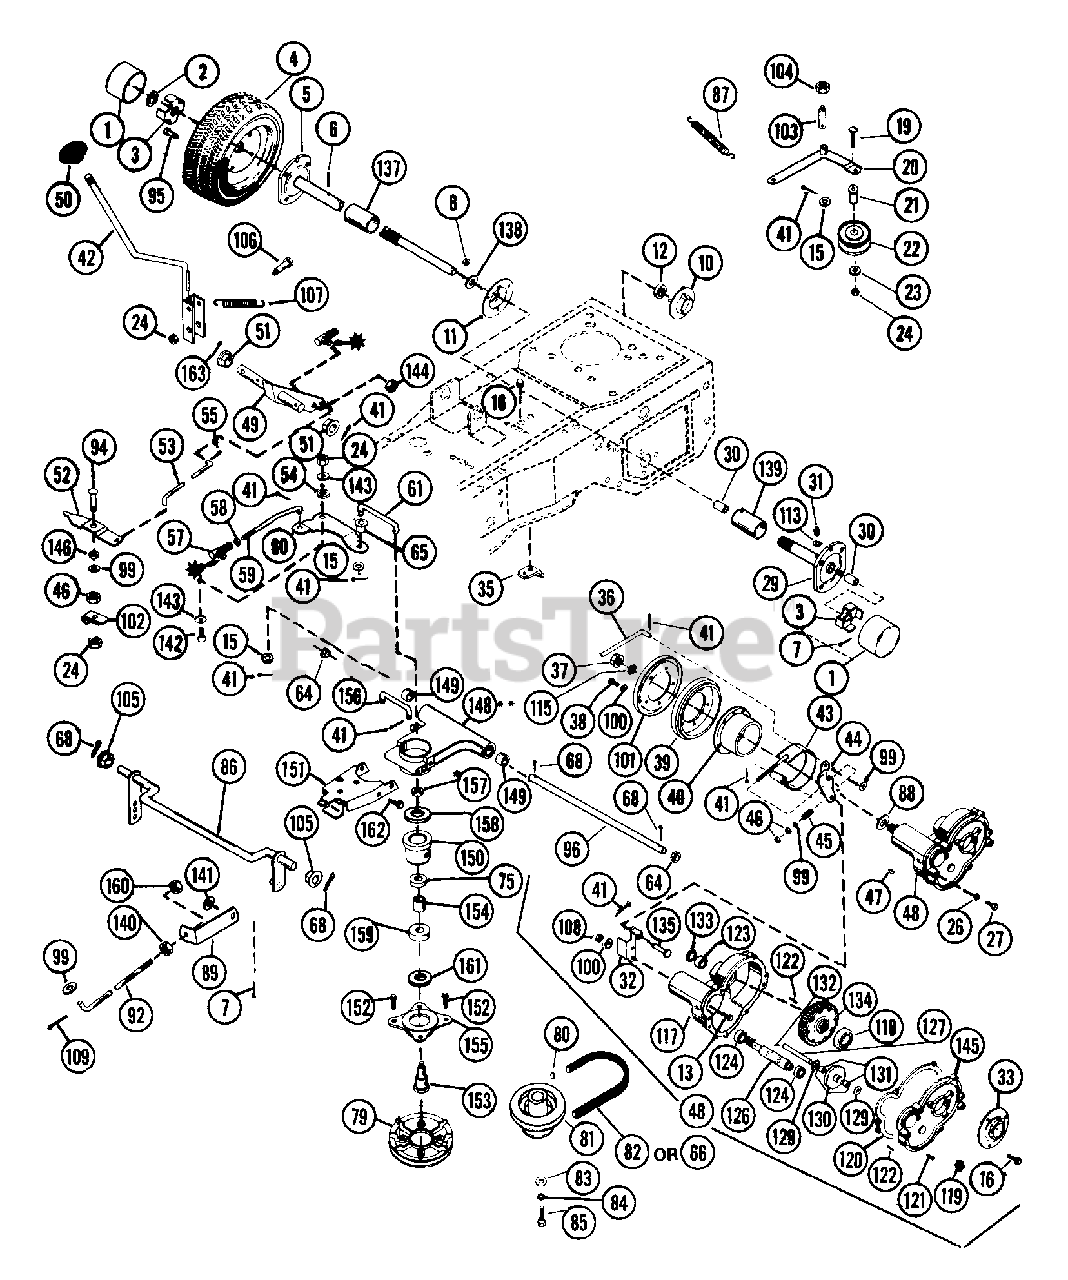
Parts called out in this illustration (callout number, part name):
1	HUB CAP
2	PUSHNUT
3	SPINDLE CUP
4	WHEEL ASSEMBLY
4	TIRE
4	TERRA TIRE & WHEEL ASSEMBLY
4	TIRE 16X6.50-8 2 PLY
5	R H AXLE
5	RH AXLE
6	PIN-ROLL .188X1.25
7	PIN-COTR .12X1.0 PL
8	NUT-LK-FLG .250-20 PL
10	BEARING FLANGE
11	BEARING FLANGE
12	BRG-BALL .876 X 1.750 X .50
13	BLT-SERRDHD SL .31-18X.75 YZ
15	WSHR-FL-STL .505X.880X.072 PL
16	BLT-SCRHFWH .25-20X.62 PL
19	BLT-RDHDSQNK .31-18X1.25 SHTPL
20	IDLER ARM
21	SPACER -SHLD .344X.500X.469
22	IDLER
23	WSHR-FL-STL .38X.875X.083 PL
24	NUT-LK .312-18 GR A PL
25	WSHR-FL-STL .391X1.500X.188 PL
26	WSHR-LK .312X.097 PL HVY
27	BLT-HEX .31-18X.75 PL GR5
29	L H AXLE ASSEMBLY
30	BSHG-SLV .690X.814X1.000 BR
31	SPIN DRIVE ZERK FITTING
32	BRAKE BRACKET
33	SEAL 1.125X2.496X.380
35	NEUTRAL STOP
36	BRAKE ROD
37	NUT-LK-NYL.625-18 PL
38	BLT-HEX .31-18X.50 PL GR2
39	FRICTION DISC
40	FRICTION DISC HUB
41	PIN-COTR .09X.75 PL
42	SHIFT LEVER
43	BRAKE BAND
44	BRAKE LEVER
45	SG-COMP .105X.585X.75
46	NUT-HEX .312-18
46	WIRE
47	KEY-WDRF .188X.875X.375 SAE11
48	GEAR CASE ASSEMBLY
49	SHIFT ARM
50	SHIFT BALL
51	FLANGE BUSHING
52	INDICATOR
53	INDICATOR ROD
54	SPACER BUSHING .5 X .32 X .21
55	PIN-COTR .06X.50
56	NUT-LK-CTR .312-24 PL
57	SNAP IN BALL JOINT
58	NUT-HEX .312-24 PL
59	SHIFT ROD
60	BELL CRANK
61	SHIFT LINK
63	SCR-TAP .312-18X.50 HWH PL TR
64	FLANGE BUSHING
65	BSHG-FLG .372X.500X.312X.625NY
67	WSHR-FL-STL .328X.875X.062 PL
68	PIN-COTR .12X1.0 PL
69	BLT-HEX .50-20X3.50 PL GR2
75	BRG-BALL .625X1.375X.44
80	KEY-STR .25X2.0X.25
81	ENGINE SHEAVE
82	V-BELT, 3L-RAW EDGE
83	WSHR-FL-STL .505X1.140X.250
84	WSHR-LK .375X.115 HVY PL
85	BLT-HEX .38-24X1.25 BLKO GR5
86	CLUTCH SHAFT
87	SG-TENS .062X.72X6.65 WLD 7
88	WSHR-FL-STL .627X.990X.032
89	CLUTCH BRACKET
92	ROD, CLUTCH
94	BLT-RDHDSQNK .31-18X1.0 SHT PL
95	BLT-WHL .50-20X.75 GR5 PL
96	TRANSFER SHAFT
99	WSHR-FL-STL .323X.625X.062 PL
100	WSHR-LK-INT .313X.030 PL
103	SHOULDER STUD
104	NUT-LK-CTR .375-16 GR A PL
105	FLANGE BUSHING
106	SHOULDER BOLT .436 X .912
107	SG-TENS .092X.69X1.75 WLD 54
108	NUT-HEAVY .312-18 PL
109	PIN-COTR .12X.75 PL
113	WSHR-LK .250X.047 LT PL
115	WSHR-LK-INT .625X.045 PL
117	SERVICE GEAR CASE
118	BRG-BALL 1.125X2.50X.63
119	BREATHER
120	GASKET
121	SCR-FLG-WHZ 10-24X.75 PL
122	PIN-GRV .188X.63
123	BSHG-SLV .875X1.125X1.046
124	BRG-BALL .625X1.375X.44
126	PINION SHAFT
127	IDLER SHAFT
129	WSHR-FL-STL .505X.875X.024 PL
130	PINION & GEAR W/BEARING ASSEMB
131	BRG-NEEDLE .50X.688X.625
132	PIN-ROLL .125X.75
133	SEAL .875X1.125X.125
134	DIFFERENTIAL ASSEMBLY
135	PIN-CLEV .371X3.25
137	TUBE .875 X 1.875 X 4.500
137	TUBE
138	WSHR-FL-STL .880X1.380X.062
139	TUBE 1.125 X 1.875 X 4.500
139	TUBE
140	NUT-HEX .312-18
141	WSHR-FL-STL .520X.810X.033
142	BLT-HEX .31-18X.75 PL GR2
143	WSHR-FL-STL .344X1.125X.063PL
144	NUT-LK-CTR .312-24 PL
145	GEAR CASE COVER ASSEMBLY
146	SPACER BUSHING .5 X .32 X .163
147	BLT-SERHFWH .31-18X.75 PL
148	CARRIER ASSEMBLY
149	BSHG-SLV .625X.750X.500 BR
150	BEARING HOUSING
151	CARRIER YOKE
152	BLT-SERHFWH .25-20X.50 PL
153	SPINDLE BOLT
154	BSHG-SLV .634X1.000X.465
155	DISC ADAPTER
156	SHIFT LINK
157	NUT-LK-CTR .50-20 PL
158	WSHR-HDND-STL-THR.515X.97X.062
159	BRG-BALL .750X1.781X.61
160	NUT-LK-NYL.312-18 PL
161	WSHR-HDND-THRST .758X1.23X.031
162	BLT-SERHFWH .31-18X.75 PL
163	PIN-COTR .09X1.0 PL
